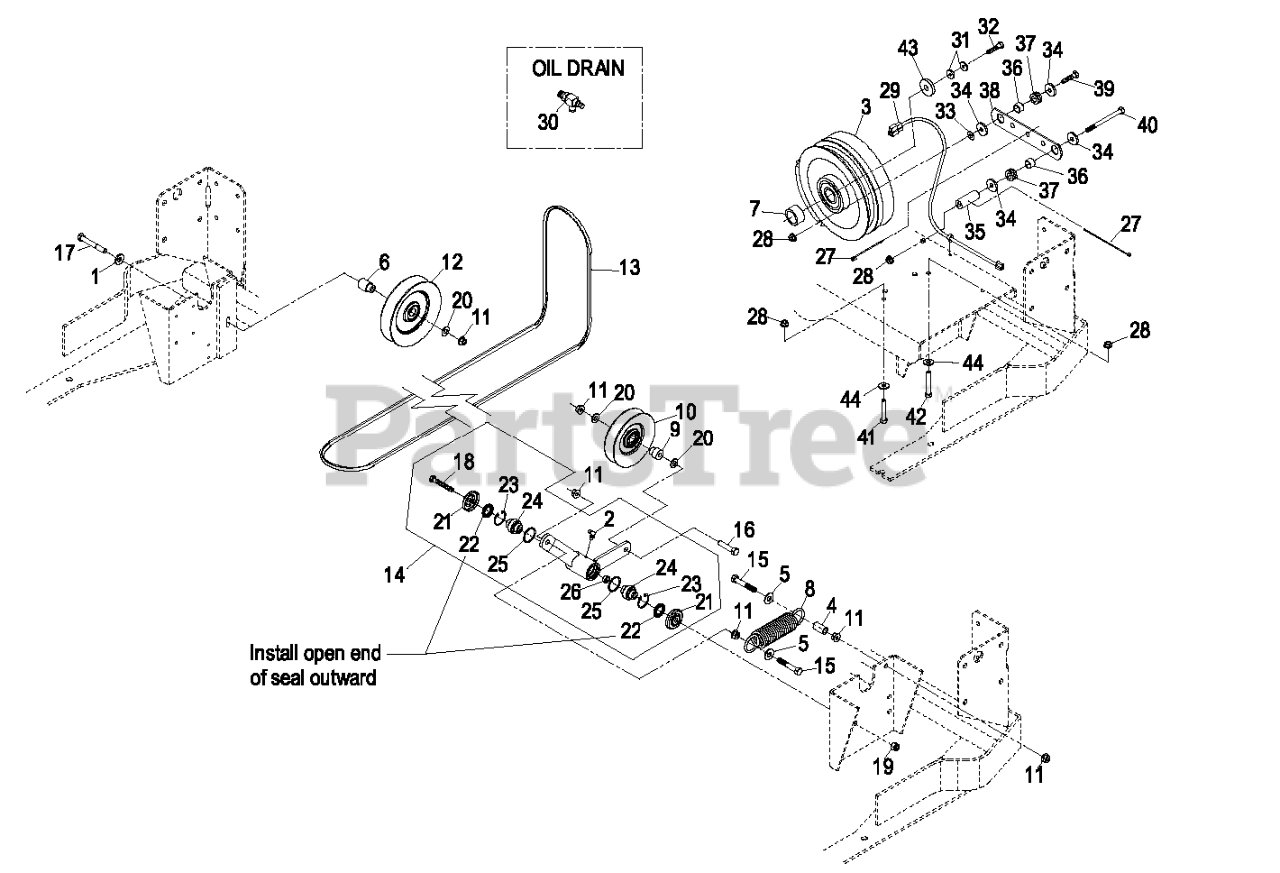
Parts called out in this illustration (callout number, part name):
1	WASHER-BELLEVILLE
2	FITTING-GREASE, 90 DEG
5	WASHER-FLAT
6	BUSHING-IDLER
8	SPRING-EXTENSION
9	BUSHING-IDLER
10	PULLEY-IDLER
11	NUT-HHF, WHIZ
12	PULLEY-IDLER
13	BELT-V B 118.75
14	KIT,MULE IDLER LZ
15	SCREW-HH
16	SCREW-HH
17	SCREW-HH
18	SCREW-HH
19	NUT-LOCK, NI
20	WASHER-FLAT
21	GUARD-TOP
22	SEAL-LIP, SINGLE
23	RING-SNAP
24	BEARING-SPHERICAL
27	TIE-PLASTIC
29	KIT,CLUTCH JUMPER HARNESS
30	VALVE-OIL DRAIN
31	WASHER-SPRING
32	SCREW-HH
33	WASHER-FLAT
35	SPACER-ANCHOR, CLUTCH
37	GROMMET
38	STRAP-CLUTCH, BRAKE
39	SCREW-HH
40	SCREW-HH
41	SCREW-HH
42	SCREW-HH
43	WASHER-CLUTCH
44	WASHER-SPRING
